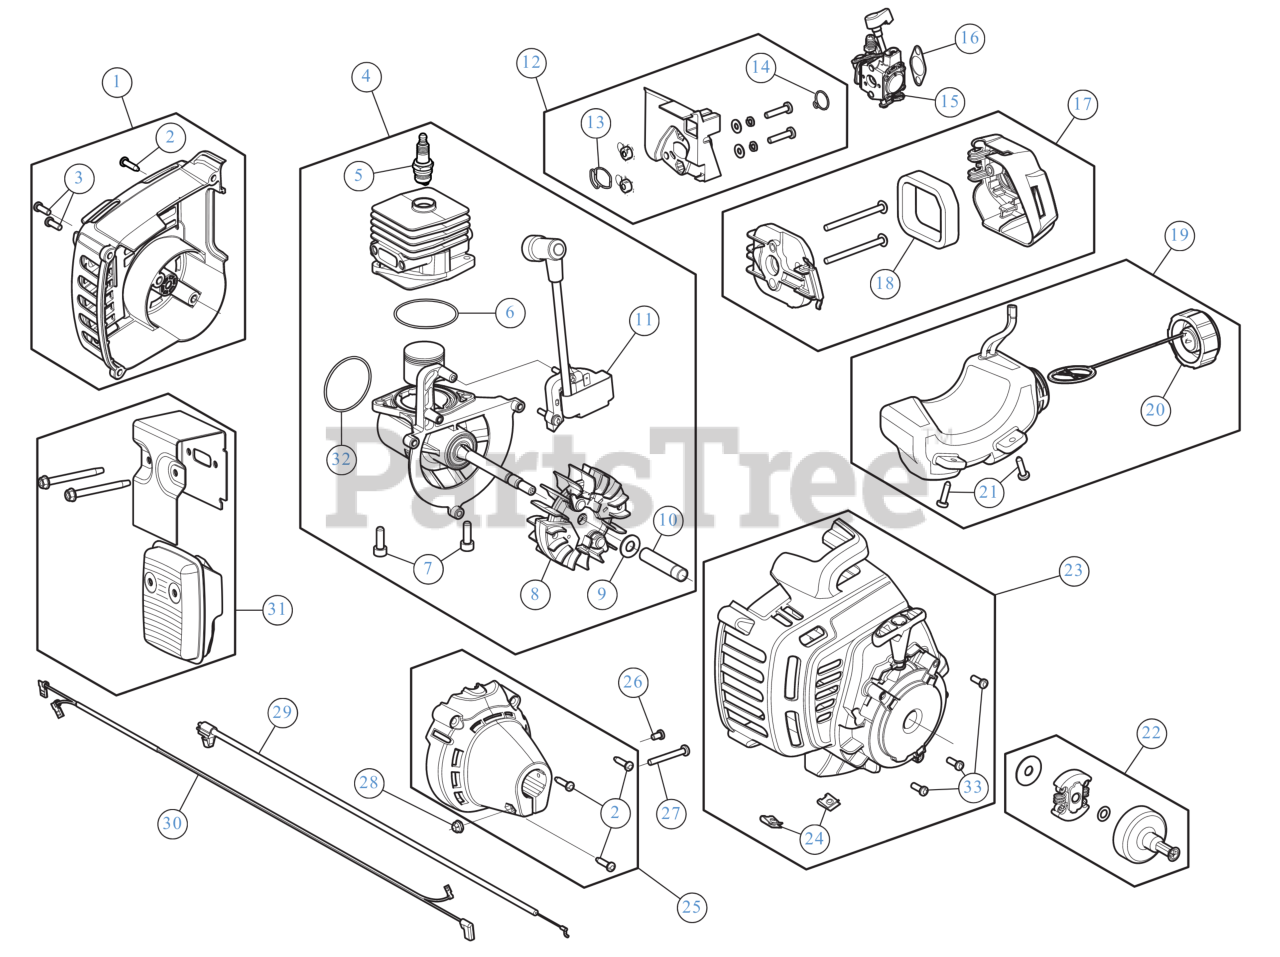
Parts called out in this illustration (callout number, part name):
1	COVER ASSEMBLY
2	SCREW, #8-16X.750 PH
3	SCREW:10-32X.562:#8P
4	SHORT BLOCK
5	SPARK PLUG
6	O-RING
7	SCREW, 1/4-20 x .75
8	FLYWHEEL ASSEMBLY
9	BELL WASHER
10	SPACER
11	MODULE 27CC DIG
12	INTAKE ASSEMBLY
13	O-RING
14	O-RING
15	CARBURETOR
16	GASKET CARB
17	AIRCLEANER COVER ASSEMBLY
18	AIR FLITER
19	FUEL TANK ASSEMBLY
20	FUEL CAP ASSEMBLY
21	SCREW:10-6 x .75
22	SMALL CLUTCH ASSEMBLY W/SMALL DRUM
23	STARTER HOUSING ASSEMBLY
24	NUT, TINNERMAN U-T
25	CLUTCH COVER
26	SCREW, 8-32 x .312 P
27	SCREW
28	HEX NUT
29	THROTTLE CABLE
30	LEAD WIRES
31	MUFFLER ASSEMBLY
32	O-RING
33	SCREW:10-32X.562:#8P
